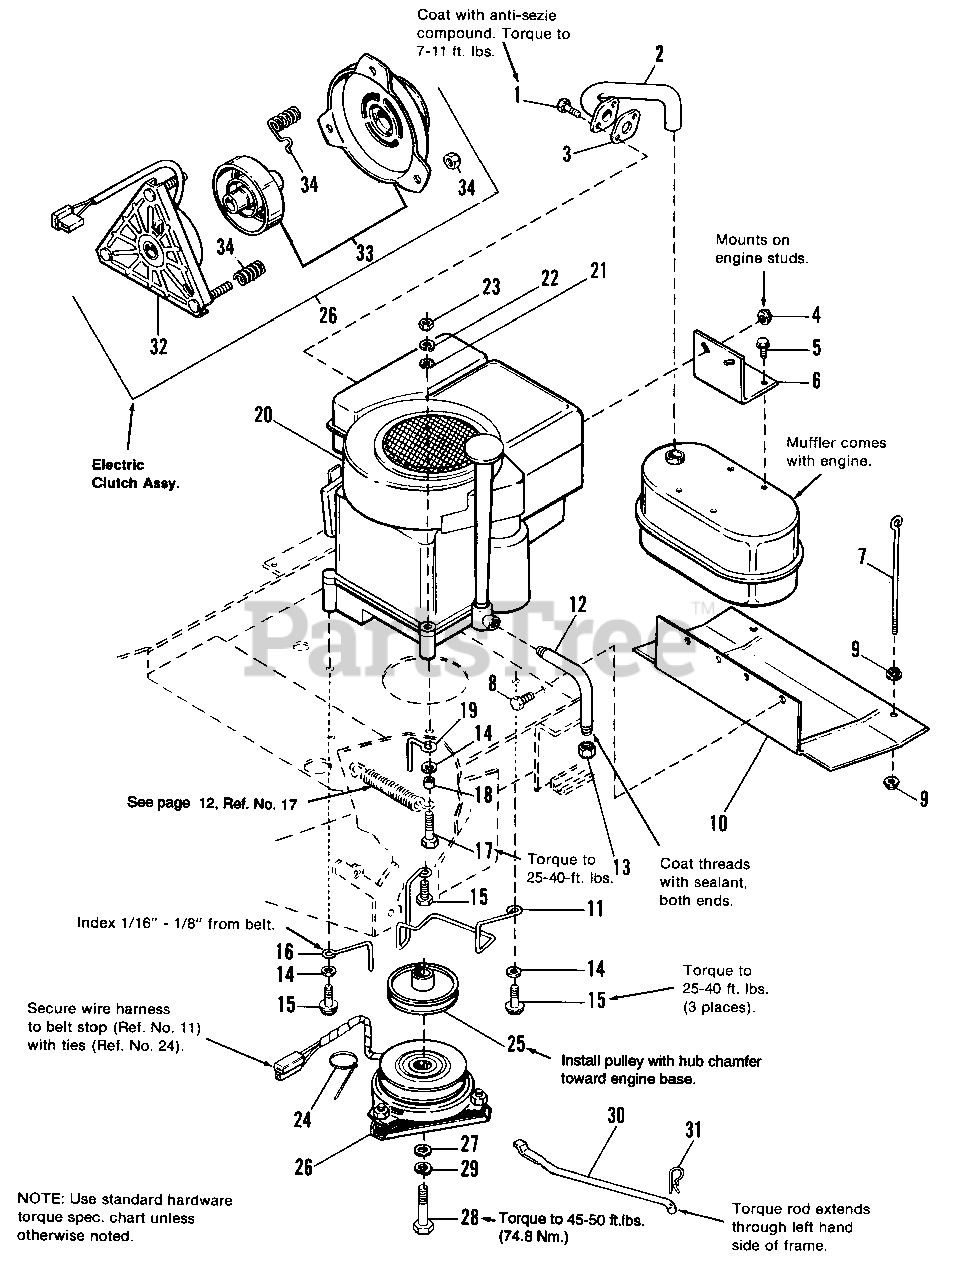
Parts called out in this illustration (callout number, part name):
1	SCREW, Whizlock, 5/16-18 x 3/4
2	PIPE, Exhaust
3	GASKET, Muffler
4	NUT, Hex Whizlock, 5/16-18
5	SCREW, Taptite, 1/4-20 x 5/8
6	BRACKET, Muffler
7	ROD, Battery Hold Down
8	SCREW, Taptite, 5/16-18 x 1/2
9	NUT, Flange Whizlock, 1/4-20
10	HEAT SHIELD ASSY.
12	DRAIN, Oil
13	CAP, Hex, 3/8
14	WASHER, 3/8
15	SCREW, Taptite, 3/8-16 x 1-1/2
17	SCREW, Taptite, 3/8-16 x 2-1/2
20	ENGINE, 12 HP Briggs & Stratton (Includes muffler)
21	LOCKWASHER, Ext. Tooth, 3/8
22	LOCKWASHER, 3/8
23	NUT, Hex Hd., 3/8-16
25	PULLEY ASSY., Drive
26	ELECTRIC CLUTCH ASSY. (Incl. Ref. Nos. 32-34)
27	WASHER, 7/16
28	CAPSCREW, Hex, 7/16 x 3-1/4
29	LOCKWASHER, 7/16
30	ROD, Torque
31	CLIP, Hair Pin
32	FIELD ASSY., Clutch
33	ROTOR ASSY./ARMATURE ASSY. KIT, Clutch
34	ACCESSORY KIT
